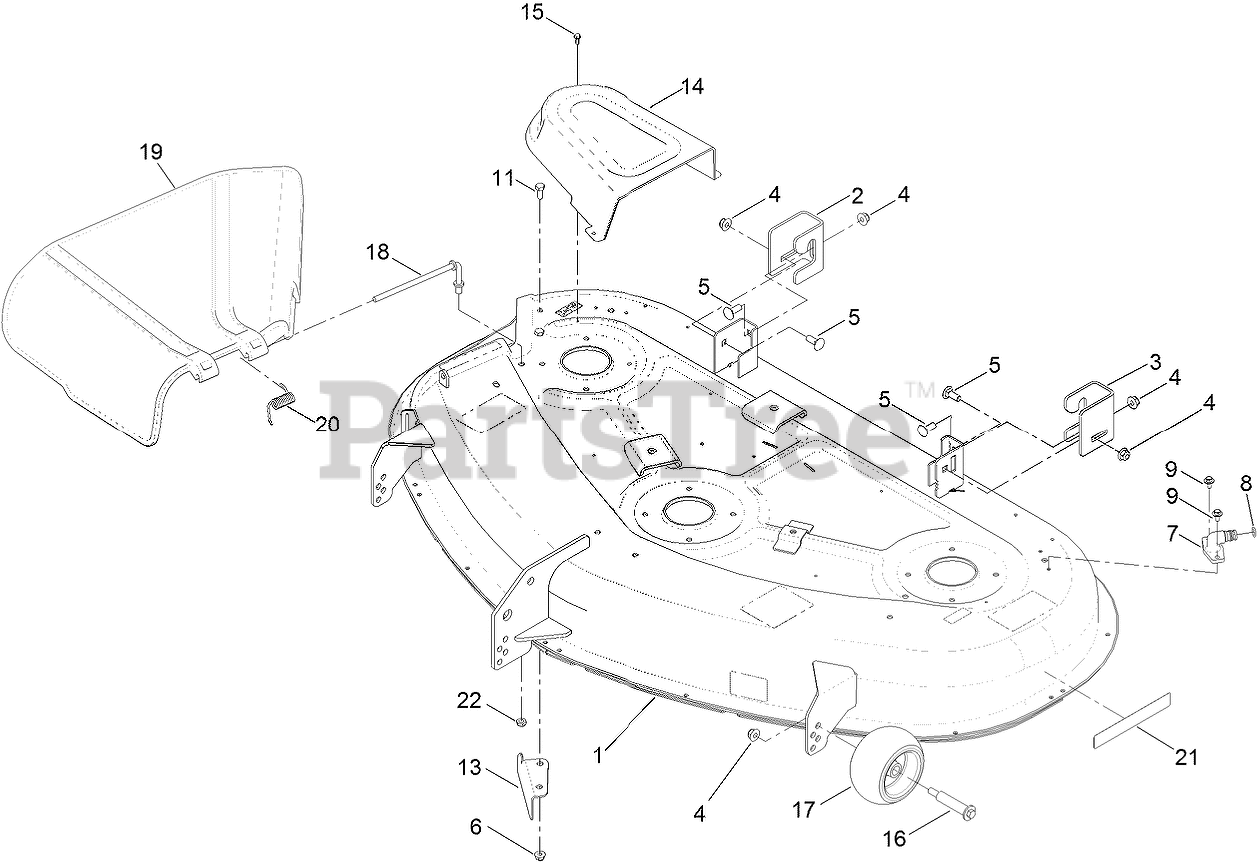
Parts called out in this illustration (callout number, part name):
1	50 INCH DECK AND DECAL ASM
2	BRACKET-HANGER, RH
3	BRACKET-HANGER, LH
4	NUT-HF, NI
5	BOLT-CARR
6	NUT-HF, NI
7	FITTING-WASHOUT
8	O-RING
9	SCREW-HHFTF
11	SCREW-HH
13	BAFFLE-CUTOFF
14	COVER-BELT
15	SCREW-TAPTITE
16	BOLT-SHOULDER
17	ROLLER-SCALP, ANTI
18	ROD-PIVOT
19	DEFLECTOR
20	SPRING-TORSION
21	DECAL-RECYCLER
22	NUT-LOCK, NI
